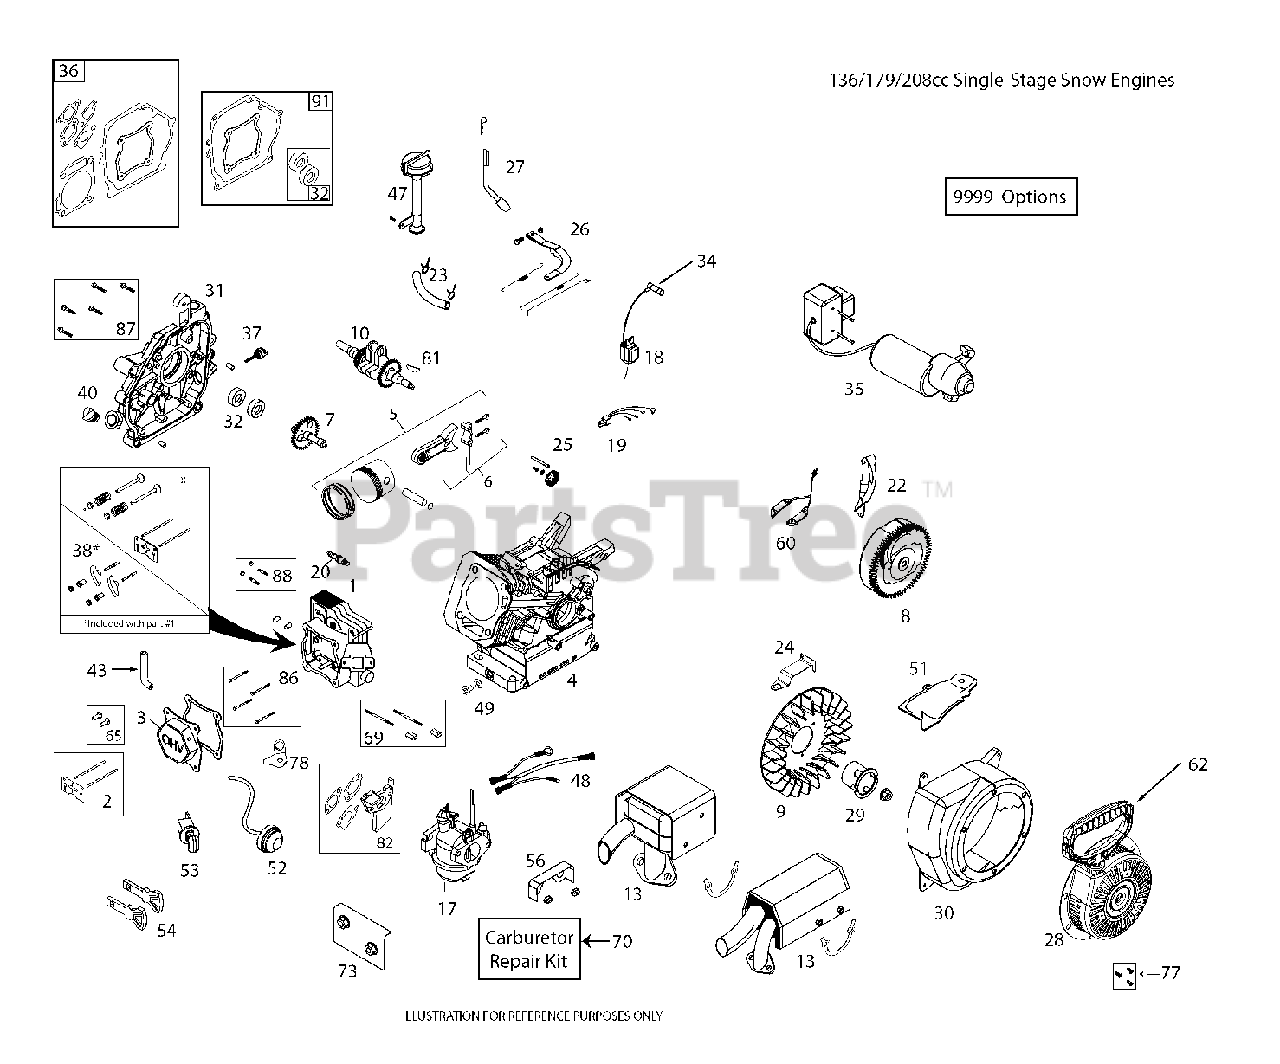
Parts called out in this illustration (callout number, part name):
1	HEAD.CYLINDER.ASSEM.LCT.136CC
2	KIT.PUSH.ROD.LCT.136CC
3	COVER.VALVE.ASSEM.LCT.136CC
4	CYLINDER.ASSEM.LCT.136CC
5	PISTON.&.ROD.ASSEM.LCT.136CC
6	Poulan TBD
7	CAMSHAFT.LCT.136CC.
8	FLYWHEEL.MAN.START.136CC.LCT
9	FAN.FLYWHEEL.LCT.SING/STAGE.SN
10	CRANKSHAFT.LCT.136CC
13	MUFFLER.LCT.SINGLE/STAGE.SNOW.
17	CARBURETOR.SNOW.LCT.136CC
18	Ignition Coil, LCT
19	Poulan TBD
20	SPARK.PLUG(2083810)
23	KIT.FUEL.HOSE.208CC.SING/STAGE
24	SPEED.CTRL.BRKT.(SKSN0150)
25	GOVENOR.GEARS ASM(SK2082900)
26	ARM.ASM.GOVNR.LCT.136CC
27	SHAFT.GOVERNOR.LCT.136CC
28	STARTER.RECOIL.S/S SNO.78".ROP
29	CUP.STARTER.LCT.136CC.SNOW
30	HOUSING.BLOWER.MANUAL.136CC
31	CRANKCASE COVER.LCT.SKSN1360.1
31	COVER.CRANKCASE.LCT.136CC
32	KIT.ENGINE.SEAL.LCT.136CC
34	SPARK.PLUG.BOOT.SNW,SKSN4691.1
35	Poulan TBD
36	KIT.GASKET.LCT.136CC
37	DIPSTICK SMALL
38	KIT ROCKER.ARM.LCT
40	NON REMOVABLE PLUG
43	TUBE.BREATHER.LCT.208
47	TUBE.OIL.HIGH.FILL.LCT.136CC
48	WIRING HARNESS LCT.SKSN0162.1
49	KIT.OIL.DRAIN.PLUG(SK2089911
51	CYLINDER COVER
52	BULB.FUEL.PRMR.W/HOSE(SKSNO306
53	SWITH.KEY.ASSEM.SNOW.SINGLE.ST
54	KEY SET(2 KEYS) SKSN0407.1
56	SHIELD.VAPOR.SNOW
60	Poulan TBD
62	STARTER.GRIP.SNOW.LCT.SKSN0603
65	TAPPET KIT.LCT.SK1361005.1 136
69	CARB.STUDS & COUPLING KIT.SNOW
70	CARB.REPAIR.KIT.LCT.SK9900.1
73	SHIELD.INTAKE.(LCT.SKSN0140.1)
77	BOLT.KIT.RECOIL.LCT.ALL.ENGINE
81	KEYS.FLYWHEEL.136/291CC.5PACK
82	SPACER.CARBURETOR.136CC.LCT
86	KIT.BOLT.CYLINDER.HEAD.(4PC)
87	KIT.BOLT.CRANKCASE.COVER.136CC
88	STUD.MUFFLER.KIT.LCT
91	CRANKSHAFT GASKET KIT.LCT.SK73
9999	HIGH.ALTITUDE.JET.(>6,000FT)
